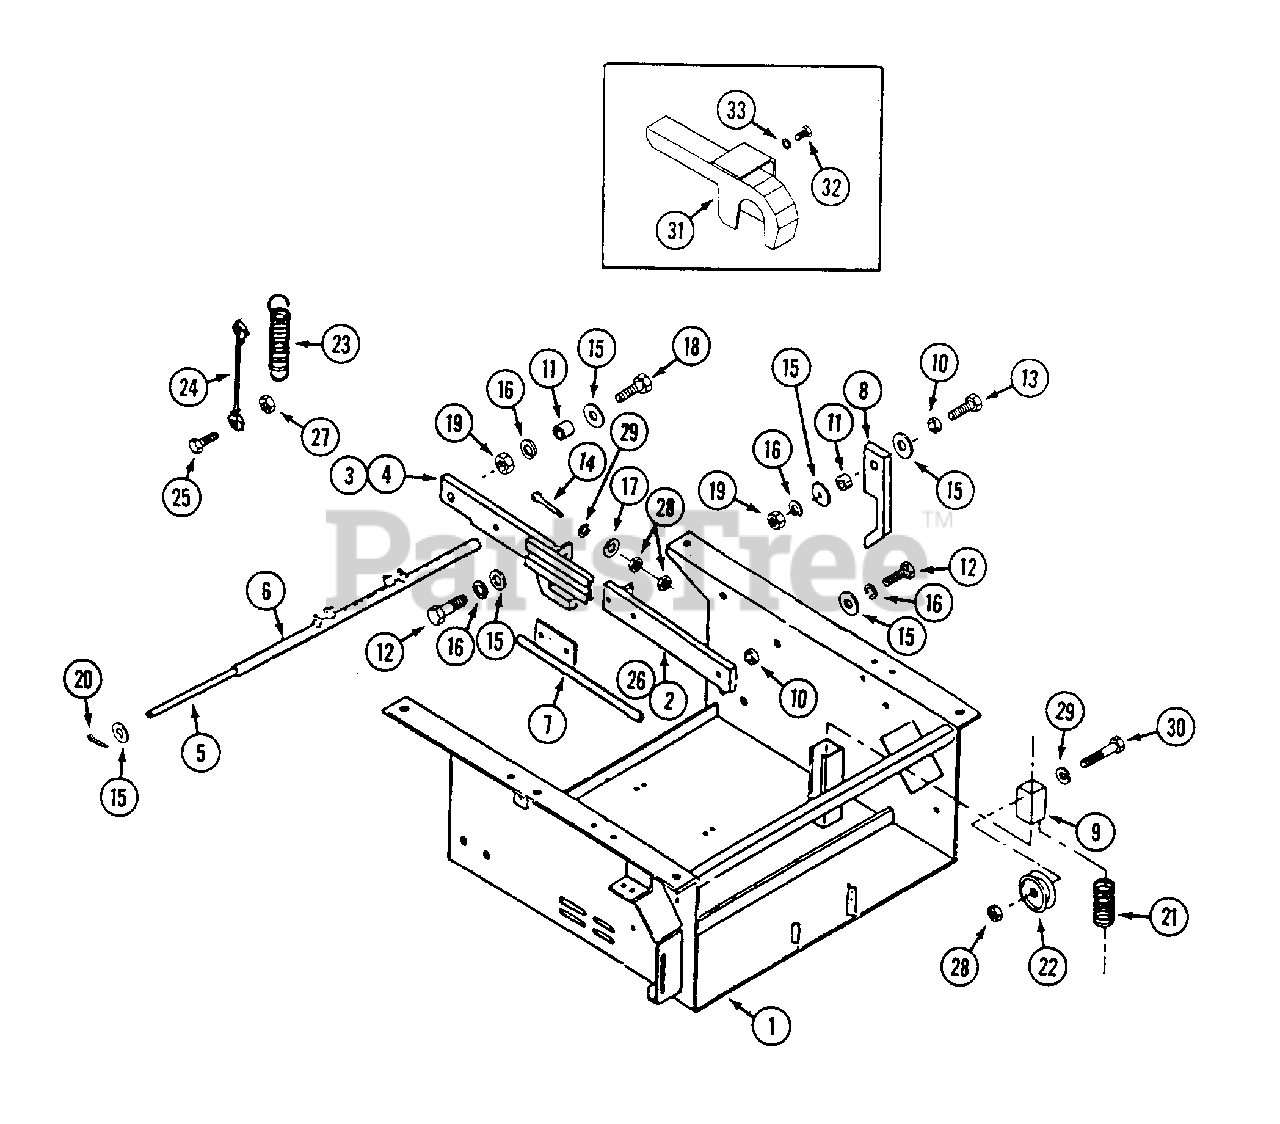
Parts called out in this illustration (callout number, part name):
1	BASE
2	ARM - deck lift R.H.
3	ARM - front L.H.
4	ARM - front R.H.
5	PIN - cross bar
8	LOCK - forward nose down
9	TUBE - drive idler
10	BUSHING - deck lift arm (3/8" long)
11	BUSHING - pivot (1/2" long)
12	BOLT - 1/2" - 13 x 1-1/4"
13	BOLT - 1/2" - 13 x 2-1/4"
14	BOLT - 3/8" - 16 x 3"
15	WASHER - 1/2"
16	LOCKWASHER - 1/2"
17	WASHER - 3/8"
18	BOLT - 1/2" - 13 x 1-1/2"
19	NUT - 1/2" - 13
20	PIN - cotter 1/8" x 1"
21	SPRING - idler tension
23	SPRING - lift assist
25	BOLT - 1/4" - 20 x 1"
26	ARM - deck lift L.H.
27	NUT - lock 1/4" - 20
28	NUT - 3/8" - 16
29	LOCKWASHER - 3/8"
30	BOLT - 3/8" - 16 x 2-1/4"
32	BOLT - 5/16" - 18 x 3/4"
33	WASHER - lock
